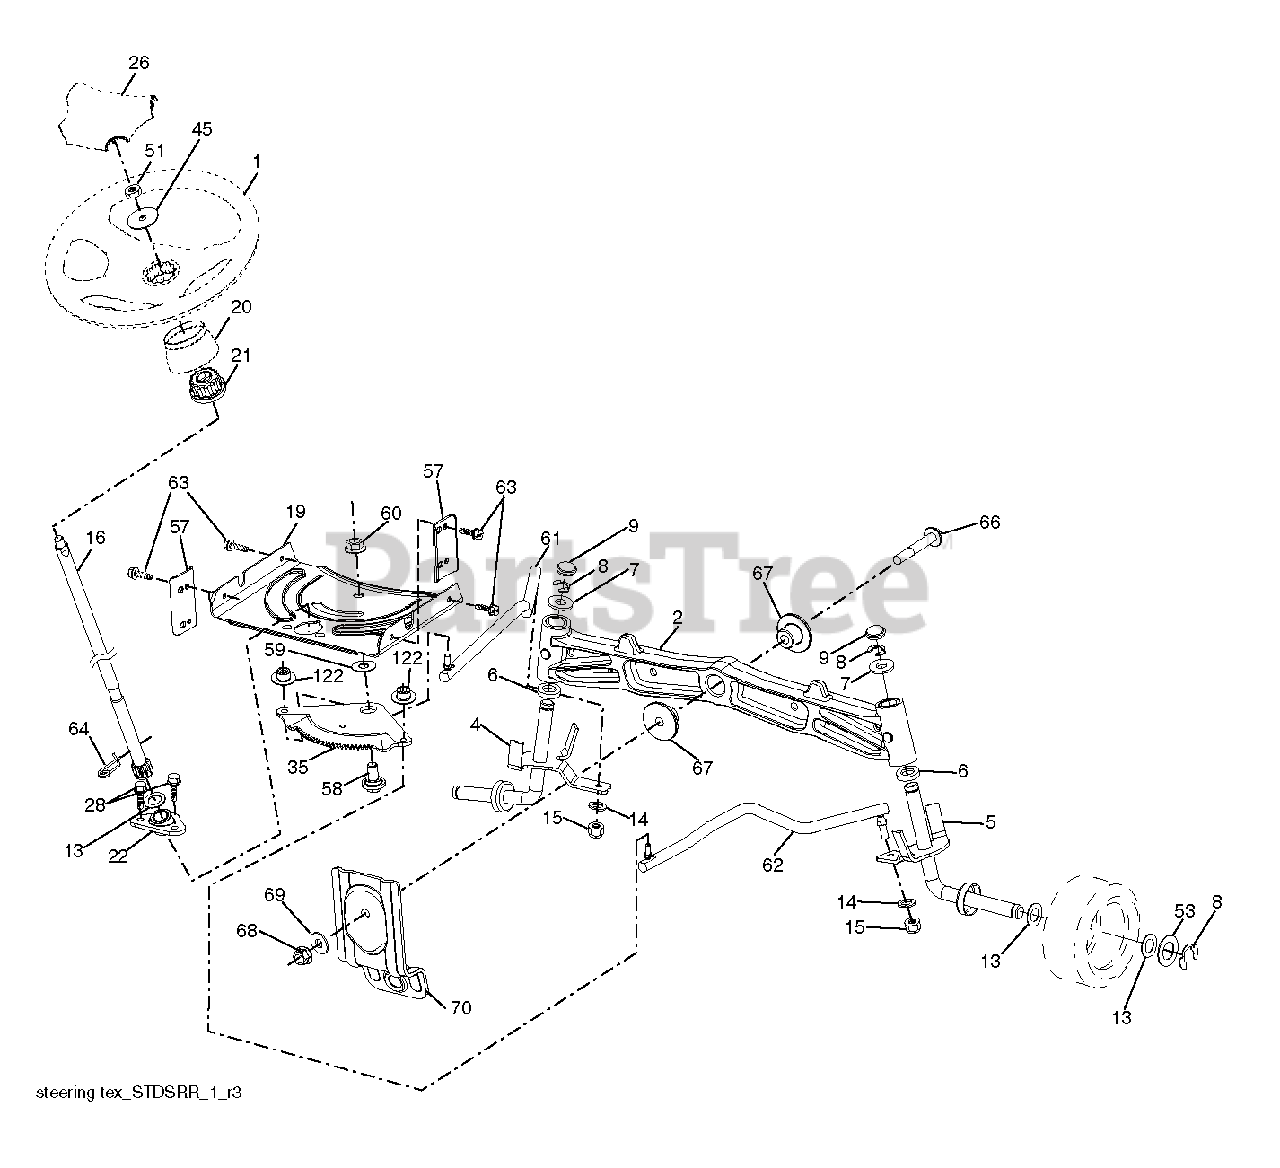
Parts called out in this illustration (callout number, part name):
1	WHEEL.STEERING.MLT.BR.YEL/OVRM
2	AXLE.CAST.IRON
4	SPINDLE.WELDED.LH.15"TEX
5	SPINDLE.WELDED.RH.15"T
8	RING CLIP
9	CAP.SPINDLE.BLACK
14	WASHER, LOCK 3/8
15	NUT CROWNLOCK 3/8-24
16	SHAFT, STEERING
19	PLATE.STEER.DDL.NLT/NG
20	BOOT, STEERING
21	ADAPTER, WHEEL STNG..
22	STEERING.SUPT.LOWER.
26	CAP.WHL.STRNG.MULTI.BRND.YEL
28	SCREW, 3/8-16X3/4
35	GEAR.SECTOR.PLATE.DDL.
45	WASHER 9/16"ID, 2 3/8""OD
51	NUT.HEX.1/2-20
53	WASHER.HARDENED
57	BRACKET.UPSTOP.TEX
58	BOLT.SHOULDER.SECTOR.P
59	WASHER.THURST.SECTOR.S
60	NUT FLANGE LOCK 5/8-11
61	DRAGLINK.LH.BALLSTUD.D
62	DRAGLINK.RH.BALLSTUD.D
63	SCREW
64	RETAINER.CLIP.SPRING.S
66	BOLT HEX FGHD 7/16-14 X 3 SERR
67	BUSHING.PM.FRONT AXLE
68	NUT.LOCK.FLANGE.7/16
69	WASHER.1.5X.505X.118
70	BRKT.DECK.SUSPENSION.F
122	CAP.GEAR.SECTOR.TEX
